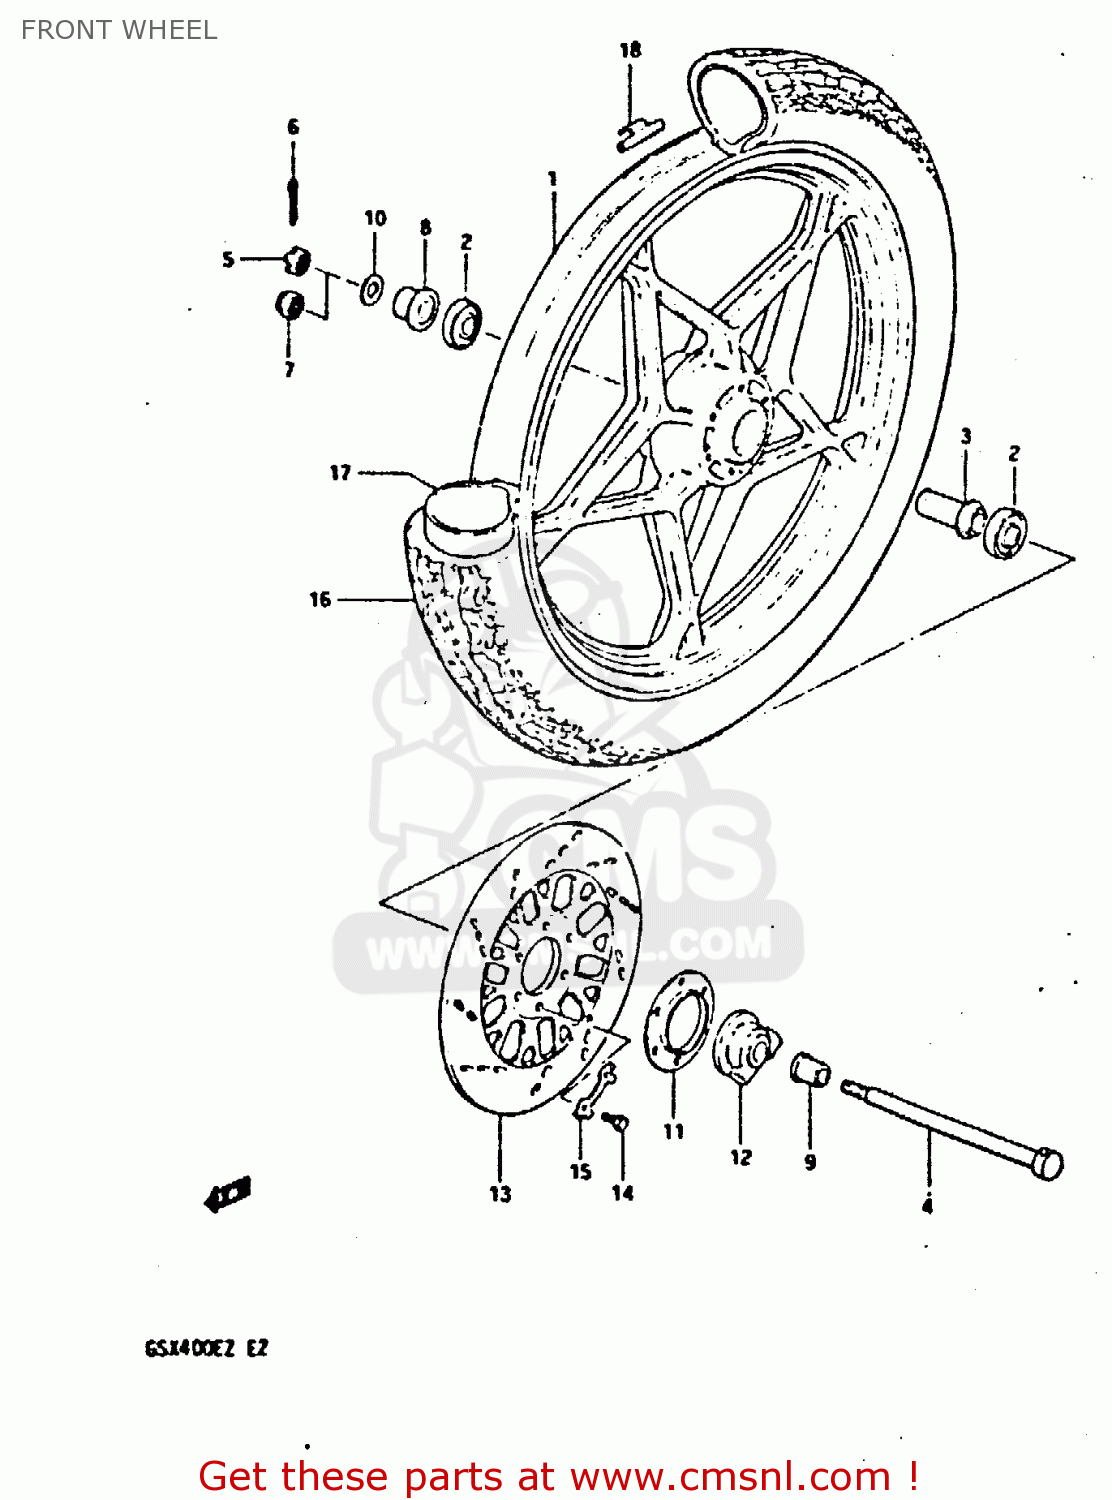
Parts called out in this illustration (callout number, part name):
1	CASTING WHEEL,FRONT 1.60
2	BEARING
3	SPACER(15.3X21.7X63)
4	AXLE,FRONT
5	NUT 12MM
6	COTTER PIN
8	SPACER,FR HUB BEARING,R
9	SPACER(15X22X30)
10	WASHER
11	DUST SEAL,SPEEDOMETER GEAR BOX
12	BOX ASSY,SPEEDOMETER GEAR
13	DISC,FR BRAKE
14	BOLT(8X25)
15	WASHER
16	TIRE,FRONT
17	TUBE,INNER
18	BALANCER,WHEEL
